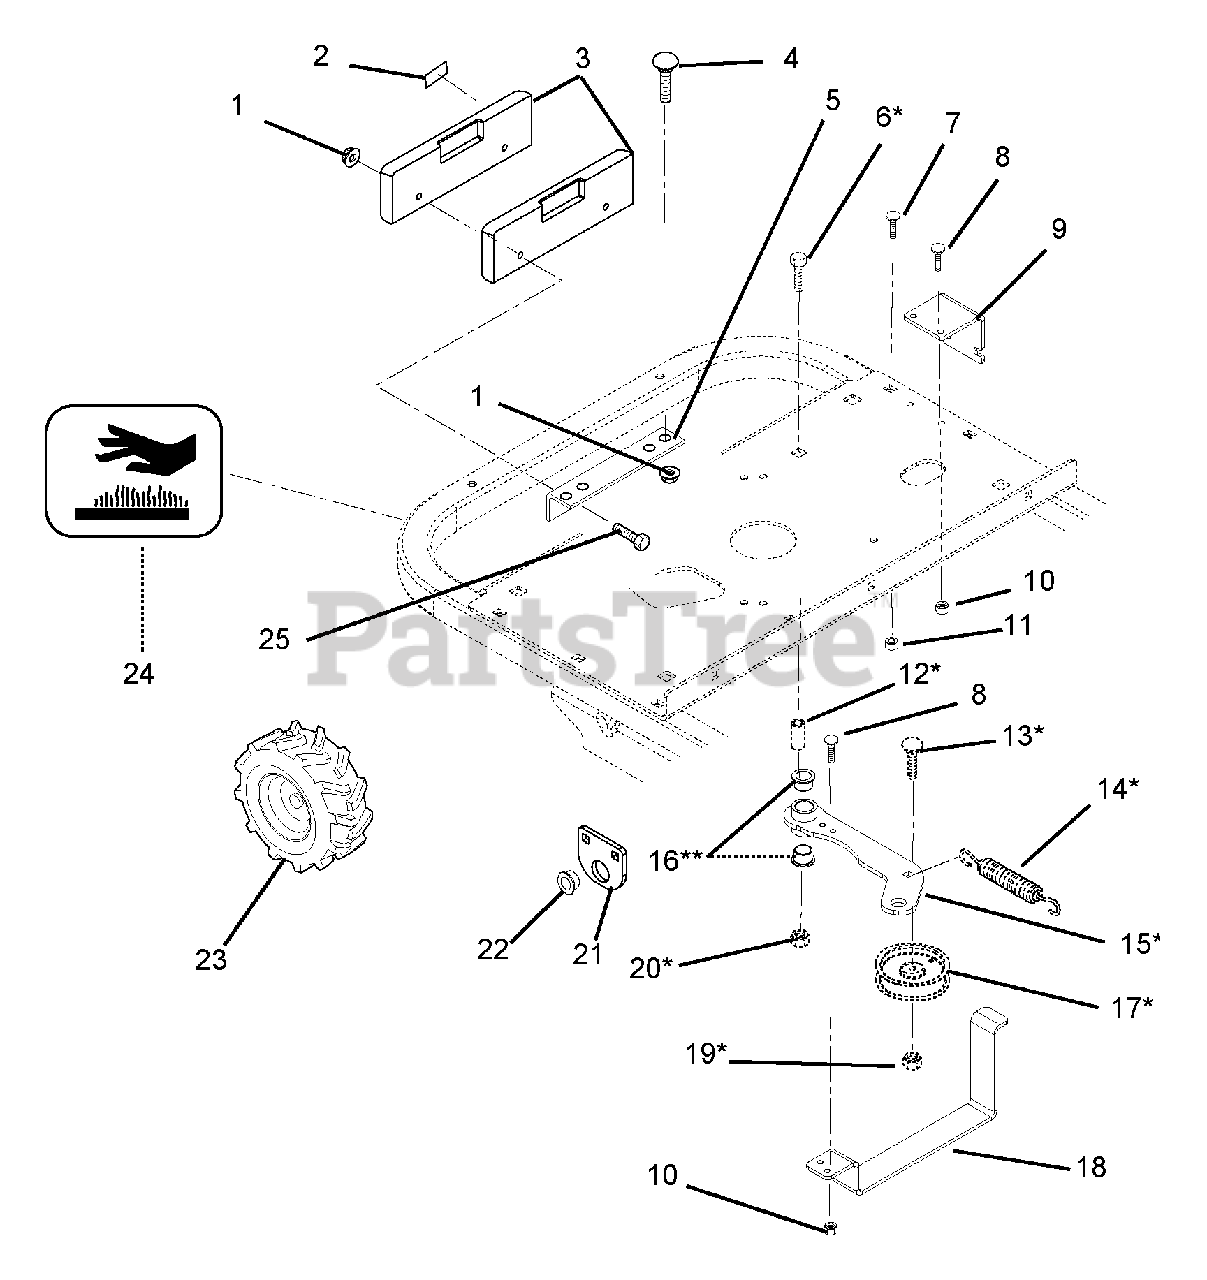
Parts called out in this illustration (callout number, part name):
1	Top Locking Flange Nut, .38-16
2	Reflector
3	Weight, Cast Iron
4	Bolt-Round Head Square Neck, .38-16 x 2.50 Grade 5
5	Angle Bracket
6	Bolt-Hex .50-13 x 2.50 Grade 5
7	Bolt-Round Head Square Neck .38-16 x 2.00
8	Bolt-Hex .25-20 x .75 Grade 5
9	Latch, Cold Start
10	Nut-Locking-Top-Flange .25-20
11	Nut-Locking-Jam-Center .375-16
12	Bushing Sleeve .50 x .75 x 1.56
13	Bolt-Round Head Square Neck .38-16 x 1.25 Grade 5
14	Spring, Extension
15	Weldment, Idler
16	Bushing, Flanged 0.75 x 0.875 x .625 x 1.125
17	Pulley, Idler 4.00
18	Handle, Cold Start
19	Nut, Locking, Jam, Center .375-16
20	Nut, Locking Top Flange .50-13
21	Bracket, Rear Pivot
22	Bushing-Flange 1 x 1.12 .62 1.50
23	Tire/Wheel Assembly, 18 x 6.5
24	Decal, Hot Surface
25	Bolt-Hex .38-16 x 4.50
47788	(Agri-Fab Part Number)
